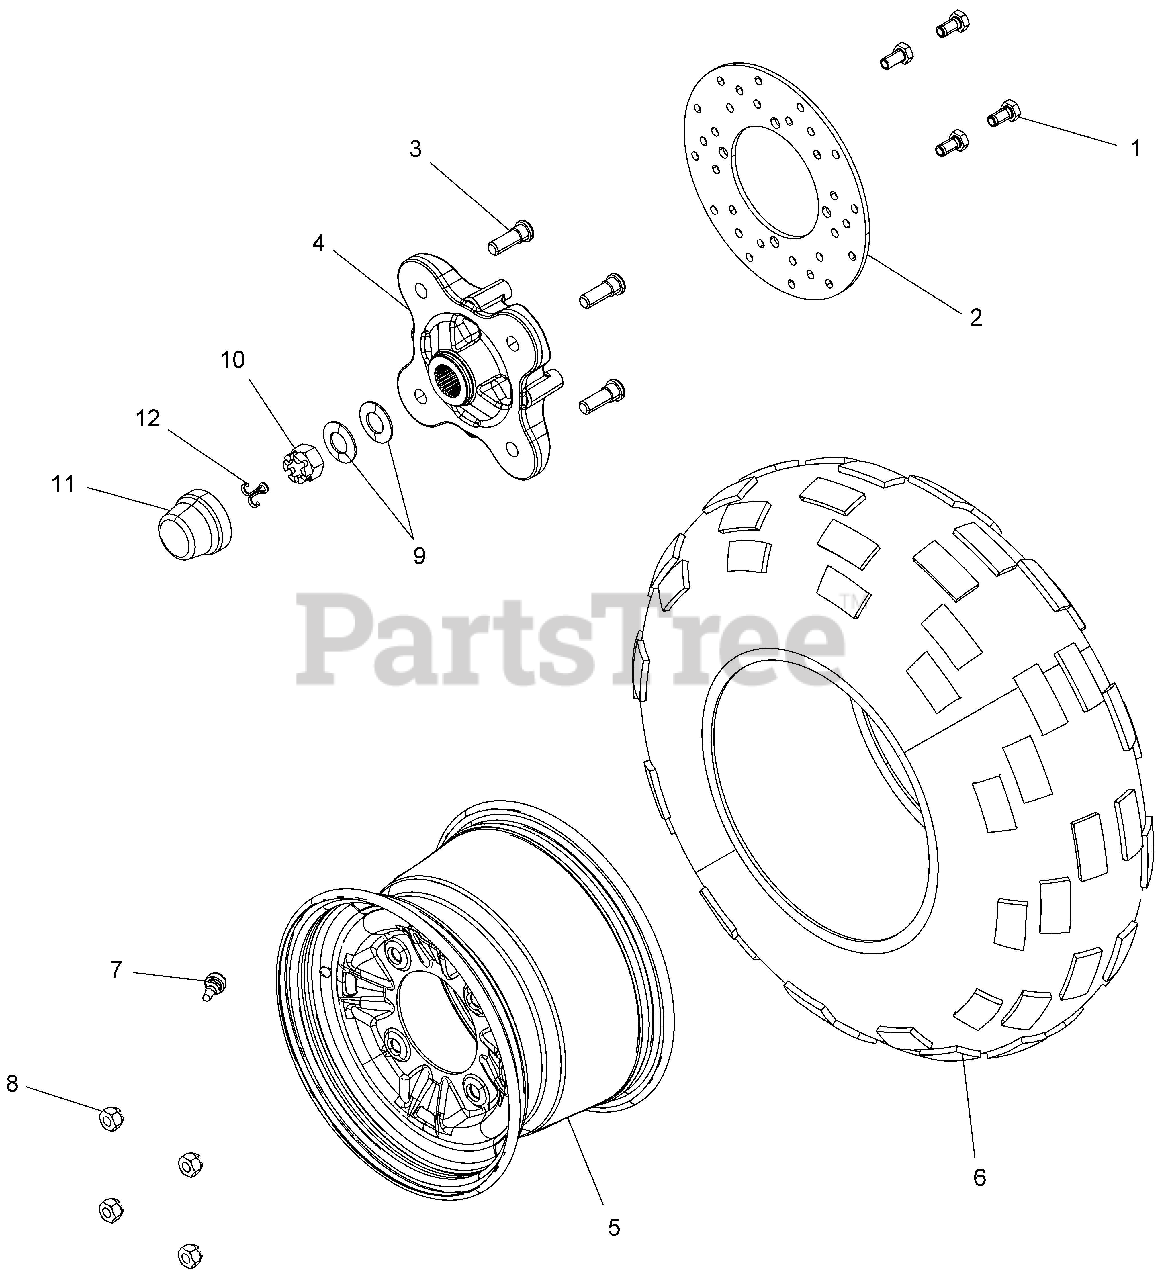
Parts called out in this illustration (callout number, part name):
1	SCR-M10X1.5X20,8.8 ZY3
2	DISC-BRAKE,REAR,8.625X.188
3	STUD-WHEEL,M12-1.5
4	HUB-WHEEL,REAR,MACH,BLK
5	WELD-RIM,RR,12X8,6"OFST,M.BLK
6	TIRE, REAR, 25X11-12
7	VALVE, RIM
8	NUT-LUG,M12
9	WASHER, CONE
10	NUT-M18X1.5,CASTLE,ZINC/YELLOW
11	CAP, DUST
12	PIN, COTTER
